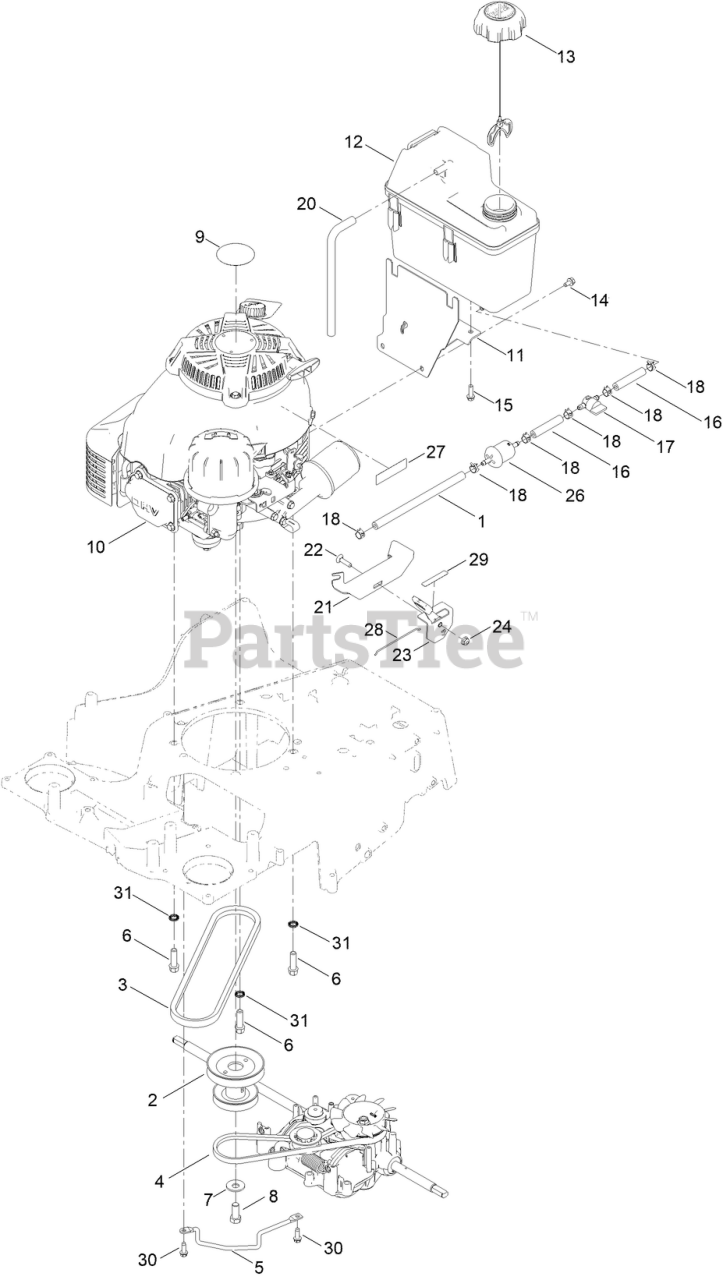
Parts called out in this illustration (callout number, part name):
1	HOSE-FUEL
2	PULLEY-ENGINE
3	V-BELT
4	BELT-V
5	ROD-GUIDE, BELT
6	SCREW-TAPTITE
7	WASHER-BELLEVILLE
8	SCREW-HH
10	ENGINE-FJ180V KAW BBC
11	MOUNT-TANK
12	TANK-FUEL
13	CAP-FUEL
14	SCREW-HWH
15	SCREW-HWH
16	HOSE-FUEL
17	VALVE-FUEL
18	CLAMP-HOSE
20	HOSE-VENT, CANISTER
21	BRACKET-MOUNT, THROTTLE
22	SCREW-CARR
23	CONTROL-THROTTLE
24	NUT-HF
26	FILTER-FUEL
27	DECAL-WARNING, ENGINE
28	WIRE-CONTROL
29	DECAL-THROTTLE, CHOKE
30	SCREW-HWHTF
31	SPACER
